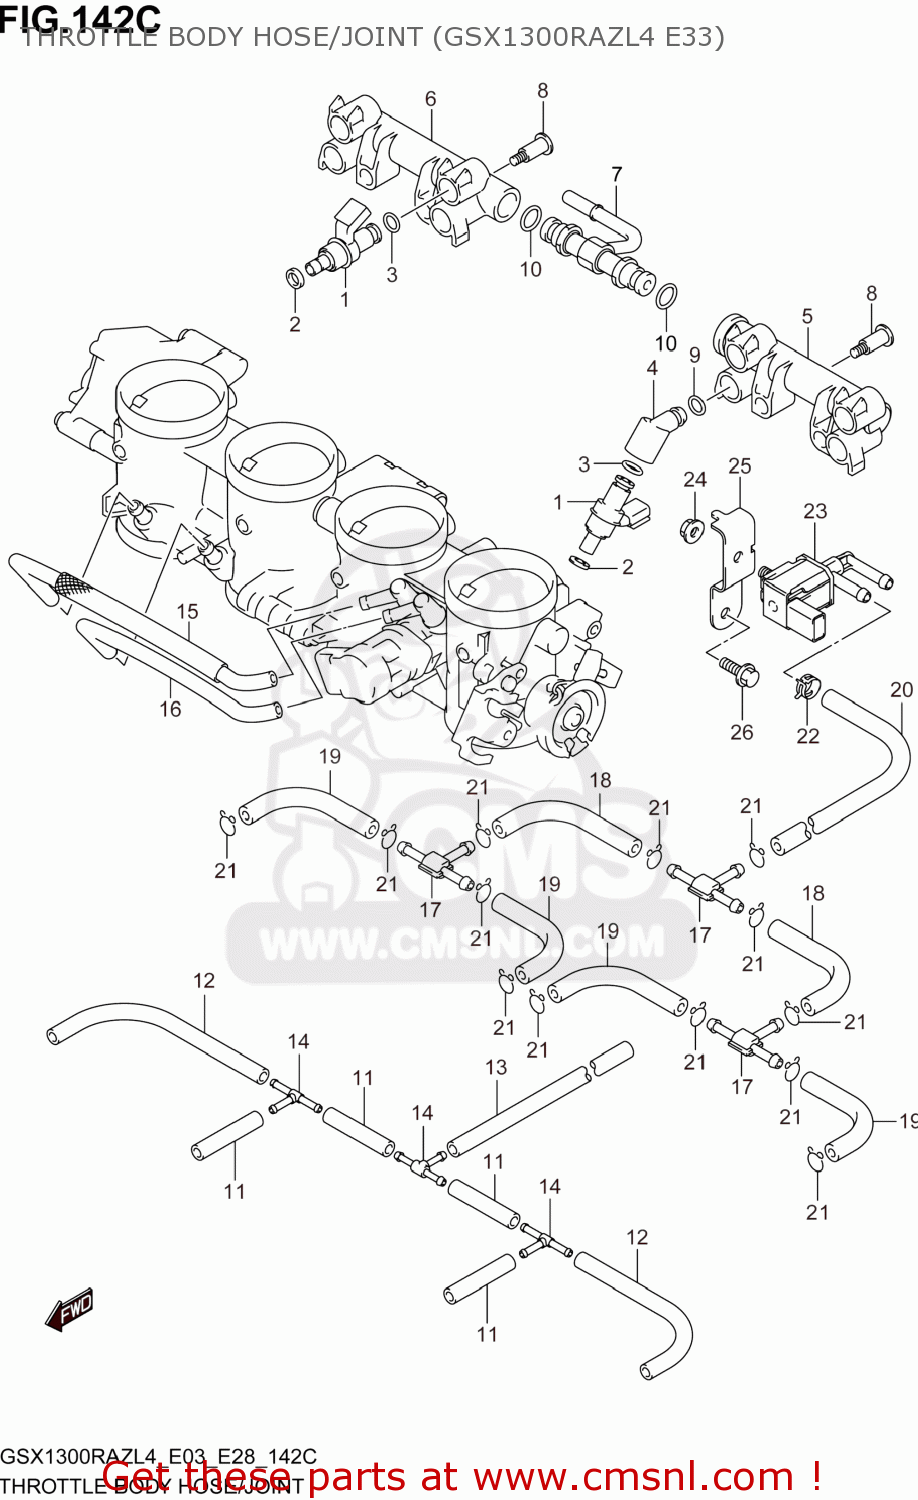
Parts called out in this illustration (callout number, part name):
1	INJECTOR ASSY
2	RING,SEAL
3	O RING
4	PIPE,FUEL
5	PIPE,FUEL
6	PIPE,FUEL
7	JOINT
8	SCREW
9	O RING
10	O RING
11	HOSE,RUBBER(L:35)
12	HOSE,RUBBER(L:100)
13	HOSE,RUBBER(3X7X170)
14	JOINT
15	TUBE
16	TUBE
17	JOINT
18	HOSE
19	HOSE
20	HOSE
21	CLIP
22	CLIP
23	VALVE,CANISTER PURGE
24	NUT
25	BRACKET,SOLENOID VALVE
26	BOLT
